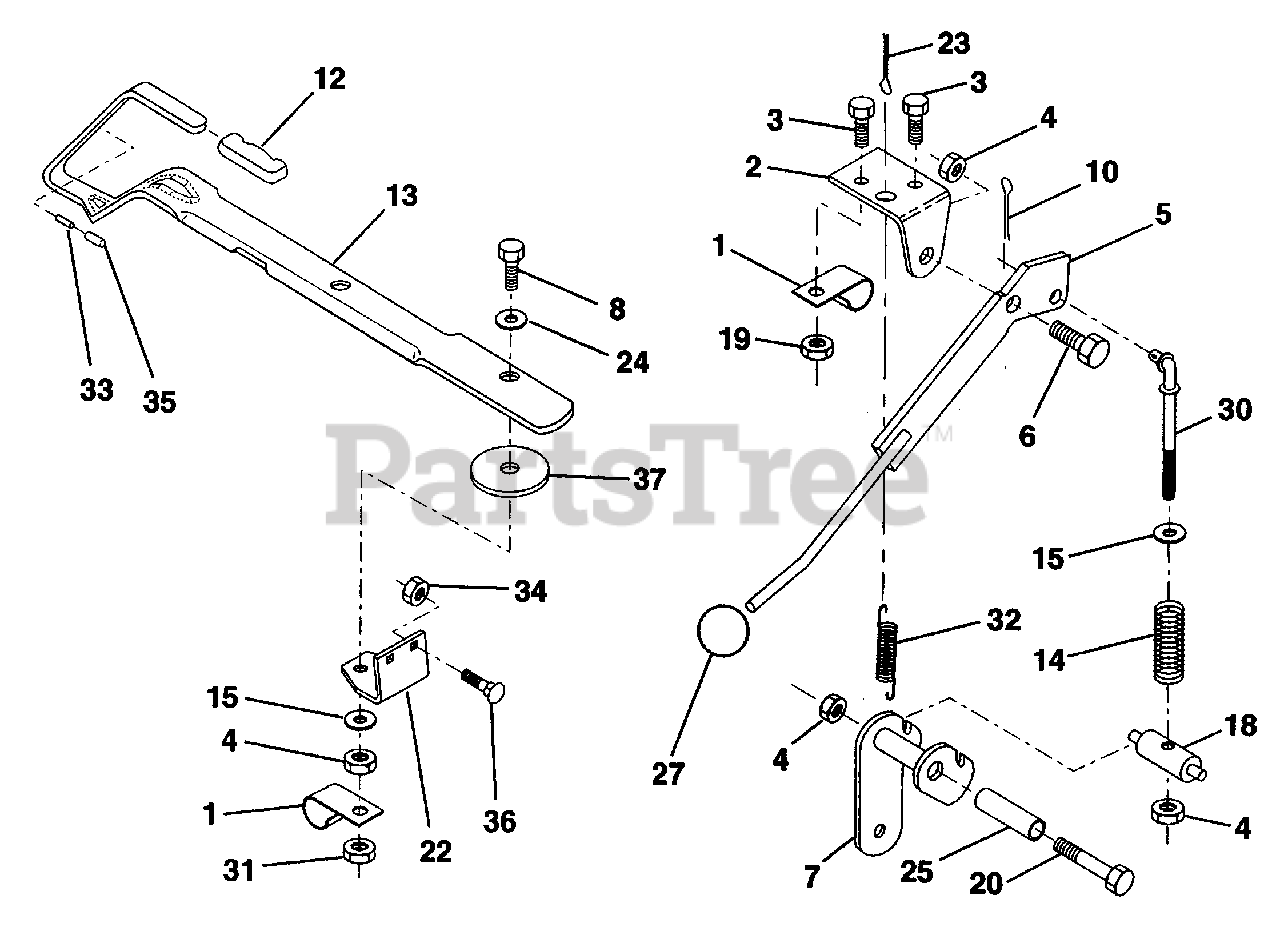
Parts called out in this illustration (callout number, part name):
1	Clip, Fuel Line (AYP part number)
2	Bracket, Mower Clutch (AYP part number)
3	Bolt, Hex, Fin. 1/4-20 UNC x 1/2 Grade 5 (AYP part number)
4	Nut, Crownlock 3/8-16 UNC
5	Assembly, Clutch Lever (AYP part number)
6	Bolt, Shoulder (AYP part number)
7	Assembly, Mower Clutch Arm (AYP part number)
8	Bolt, Hex Head 3/8-16 x 1-1/2 (AYP part number)
10	Pin, Cotter 1/8 x 3/4 (AYP part number)
12	Handle, Lift Lever (AYP part number)
13	Assembly, Lift Handle (AYP part number)
14	Spring, Compression, Clutch (AYP part number)
15	Washer 13/32 x 1 x 16 Gauge (AYP part number)
18	Trunnion (AYP part number)
19	Nut, Crownlock 1/4-20 (AYP part number)
20	Bolt, Hex, Fin. 3/8-16 UNC x 2-3/4 (AYP part number)
22	Bracket, Lift Lever (AYP part number)
23	Pin, Cotter 3/32 x 3/4 (AYP part number)
24	Washer 25/64 x 1-1/4 x 12 Gauge (AYP part number)
25	Tube, Spacer (AYP part number)
27	Knob (AYP part number)
30	Rod, Tension, Clutch (AYP part number)
31	Nut, Centerlock 3/8-16 (AYP part number)
32	Spring, Extension, Return (AYP part number)
33	Pin, Roll (AYP part number)
34	Nut, Crownlock 5/16-18
35	Cap, Vinyl, Red (AYP part number)
36	Bolt, Carriage 5/16-18 x 3/4
37	Washer 13/32 x 2-3/8 x 8 Gauge (AYP part number)
